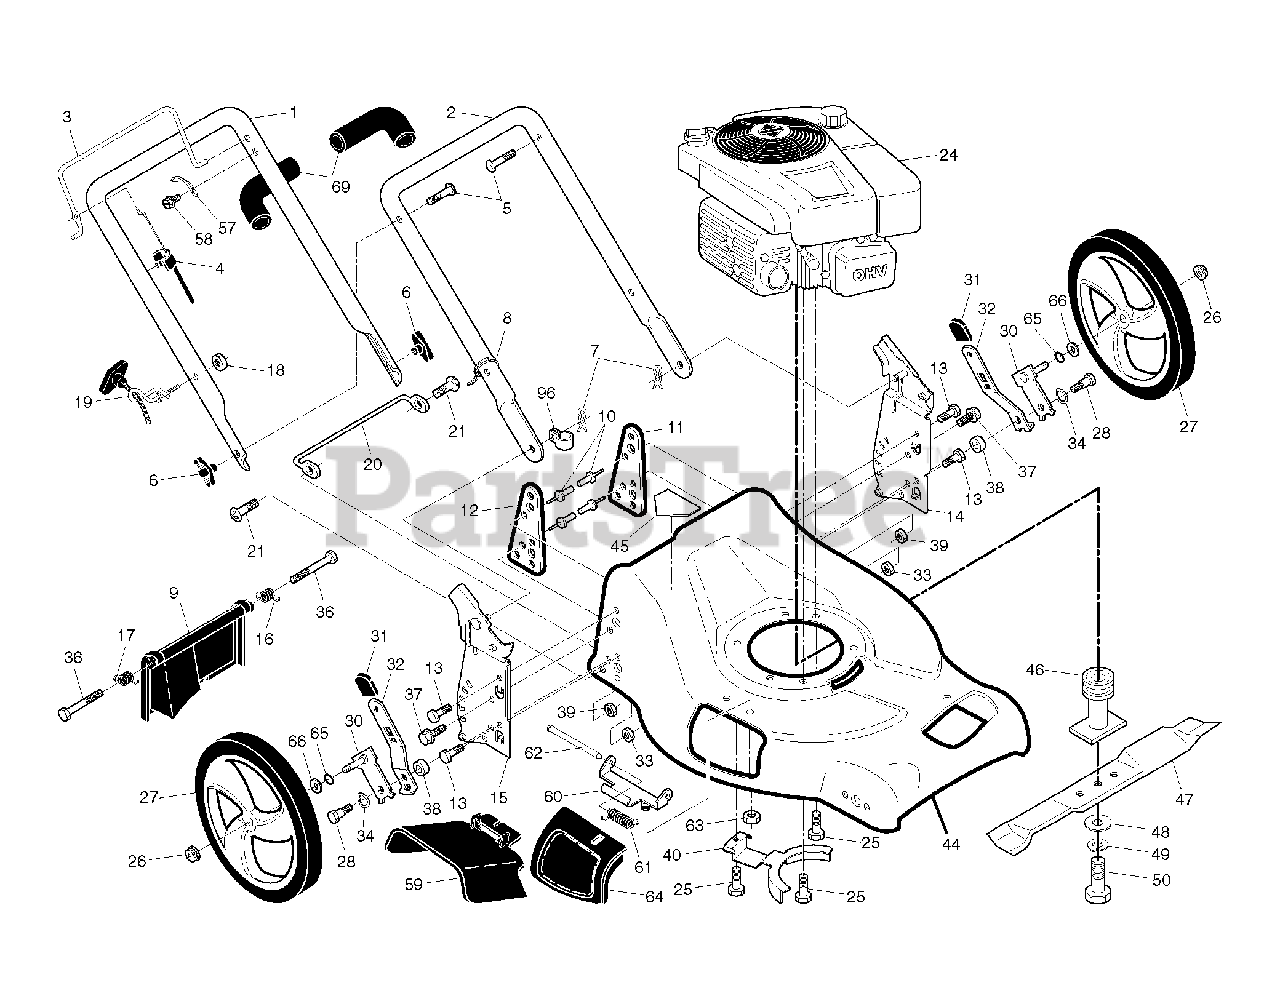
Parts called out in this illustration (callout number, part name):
2	LOWER HANDLE
4	CABLE.ASM.ZONE.CONTROL
5	BOLT, HANDLE 5/16-18X1.75
6	KNOB, DEFLECTOR
7	HAIRPIN COTTER
8	TIE GUIDE
9	REAR DOOR ASSEMBLY
10	RIVET BLIND
11	SUPPORT BRACKET LH
12	BRACKET.SUPRT.RH.21.FWGD
13	SCREW 14-20 X 5/8
14	RP BRACKET.ASM.HNDL/HW.LT.21.
15	BRACKET.ASM.HNDL/HW.RT.21.PNT
16	SPRING.REAR.DOOR.EZ.21.LT
17	SPRING.REAR.DOOR.EZ.21.RT
18	NUT
19	GUIDE.ROPE.STD.BLK.ZIN
21	SCREW
25	BOLT 3/8-16X1-1/8
26	NUT.HEX.FLANGE.3/8-16.LOCKNUT
28	SHOULDER BOLT 5/16-18
30	ARM.ASM.AXLE.REAR.5/9.POS.BZP
31	SELECTOR KNOB
32	SELECTOR SPRING
33	NUT.71038.31-18.HEX.NYLOCK
34	WASHER FLAT
37	BOLT
38	SPACER.HEIGHT.ADJUSTER
39	NUT.FLANGE.5/16
40	BRACKET.ENG/BELTKEEPER
45	DECAL.INTERNATIONL.CUTFINGER
47	BLADE.21.PUSH
48	WASHER,HARDEN
49	LOCKWASHER
50	SCREW, HEX HD 3/8-24 X 1-3/8
57	BRACKET.UPSTOP.RT
59	DISCHARGE DEFLECTOR
60	HINGE BRACKET ASSEMBLY
61	SPRING.TORSION
62	ROD.HINGE.21
63	LOCKNUT
64	DOOR.MULCH.21.REAR
65	O-RING..070X.487.NEOPRENE
66	WASHER PM
69	GRIP.HANDLE.FOAM.WIDE.(1 SIDE)
96	CLIP.CABLE.BLK
